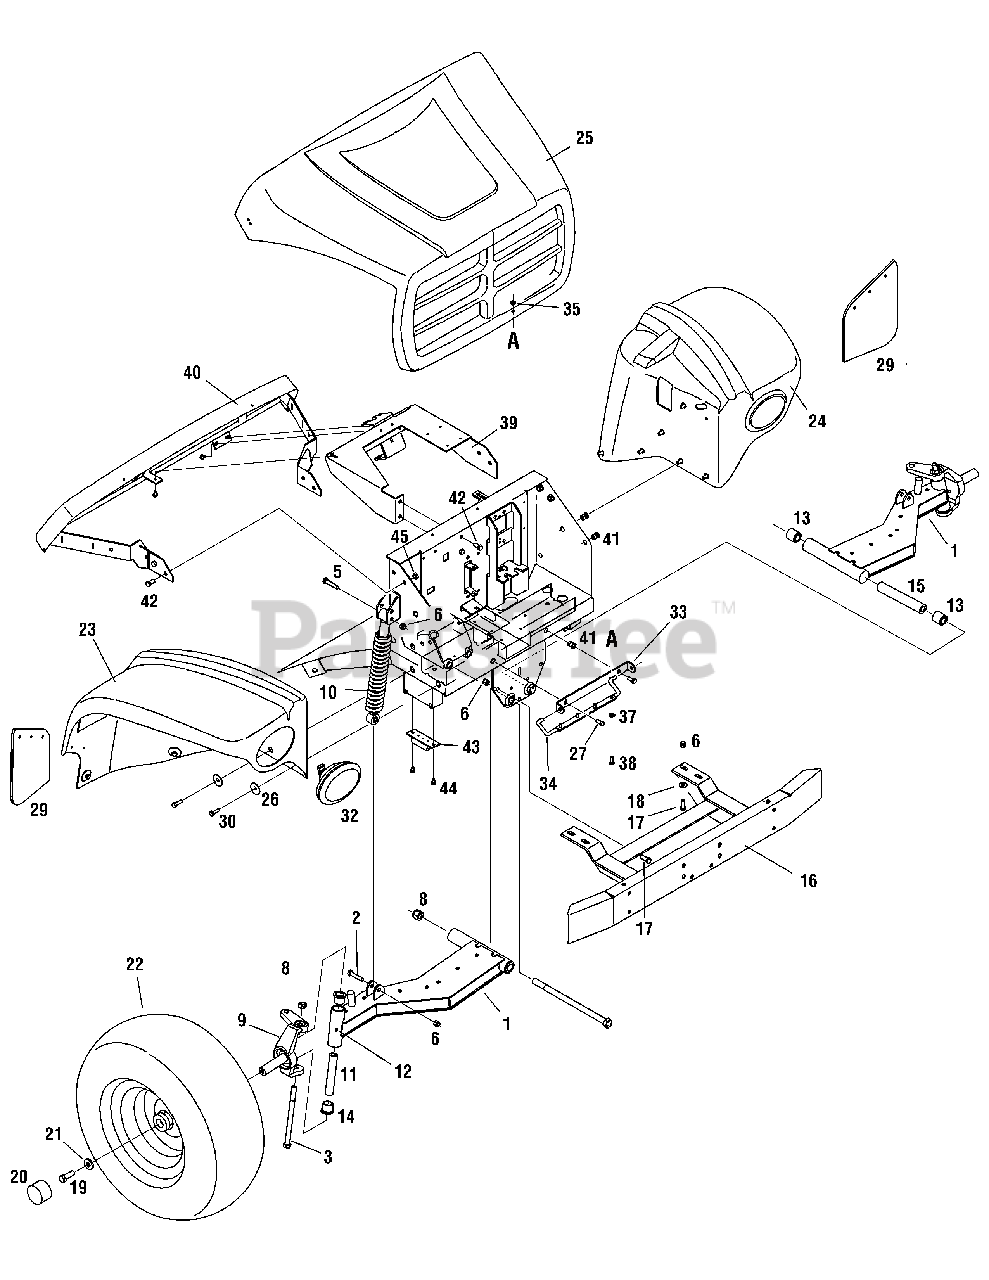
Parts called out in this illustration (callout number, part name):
1	Axle Assembly, Right-front (Incl. Ref 12 - 15)
1	Axle Assembly, Left-front (Incl. Ref 12 - 15)
2	Hex Screw, 3/8-16 x 1.75
3	Hex Screw, 1/2-13 x 7.0, Gr5
4	Hex Screw, 5/8-11 x 11.13, Gr5
5	Hex Screw, 3/8-16 x 2.25
6	Nut, Hex Lock, Nylon, 3/8-16, Gr5
7	Nut, Hex Lock, Nylon, 5/8-11, Gr5
8	Nut, Hex Lock, 1/2-13
9	Steering Control Knuckle, RH
9	Steering Control Knuckle, LH
10	Shock Absorber, 2.9 Stroke
11	Tube, .875 x .50 x 4.75
12	Grease Fitting
13	Bearing, .63 ID x 1.19 OD
14	Bushing, Steering
15	Spacer, .645 ID x 1.063 OD
18	Flat Washer, .406 x .875 x .059
19	Hex Screw, 1/2-13 x 1.25, Gr5
21	Flat Washer, .531 x 1.25 x .181
22	Wheel Assembly, 22 x 11 x 10,RH (Model 435 D)
22	Wheel Assembly, 22 x 11 x 10,LH (Model 435 D)
22	Wheel Assembly, 22 x 10 x 8, Turf (Model 435 A)
23	Panel Assembly, Right Fender, Green
24	Panel Assembly, Left Fender, Green
25	Panel Assembly, Hood, Green
26	Hex Screw 5/16-18 x 1.00 Gr 5
27	Hex Screw, 5/16-18 x .75
28	Flat Washer, .350 x 1.25 x .06
30	Washer, Bell, .39 x 1.38 x .062
31	Flat Washer, .194 x .62 x .063
32	Headlamp Assembly
35	Nut, Hex Lock, 1/4-20
36	Cotter Pin, Internal, 1.42
37	Washer, Flat, .271 x .63 x .065
38	Hex Screw, 1/4-20 x .75
41	Insert Nut, 5/16-18
42	Hex Screw, 3/8-16 x .75
43	Screw, Self-tapping, 1/4-20 x .5
44	Suspension Bumper
45	Flange Lock Nut 3/8-16
